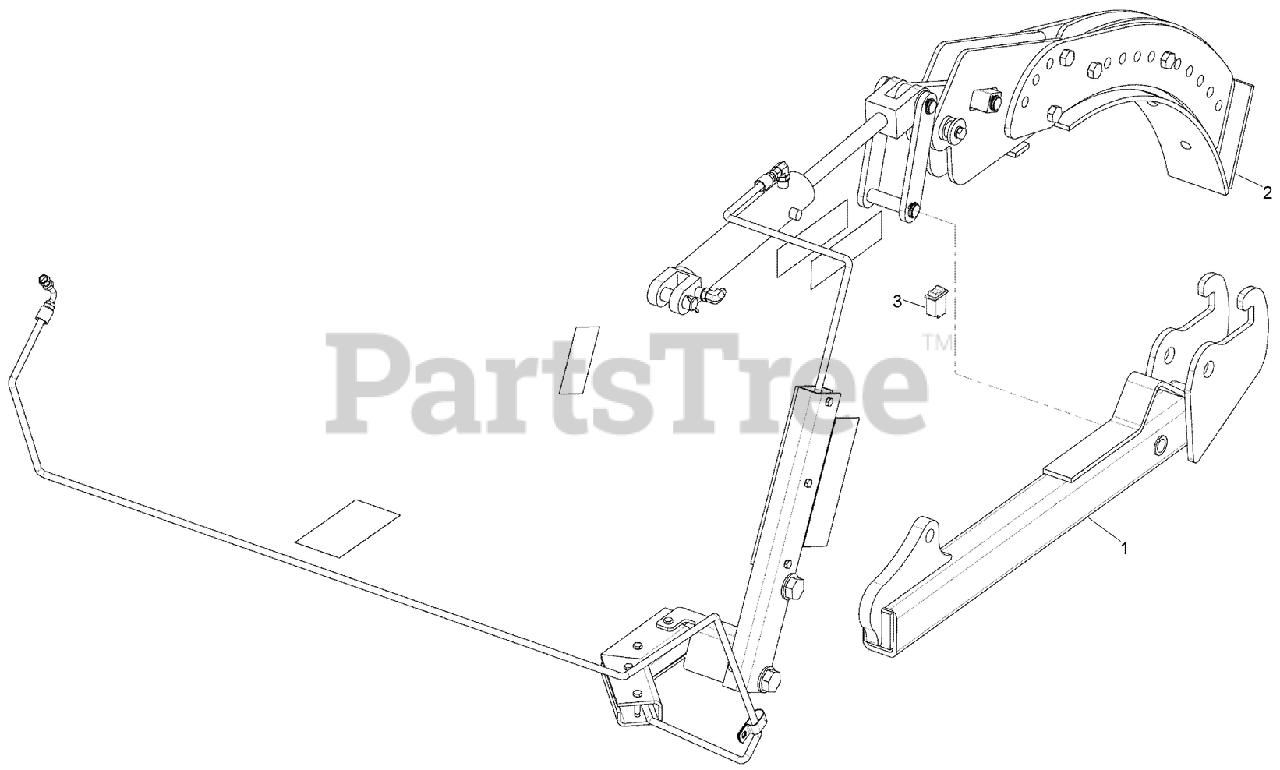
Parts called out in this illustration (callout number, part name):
1	WELDMENT - Tube, 4 Ft Crumber
2	KIT - Hydraulic Crumber
3	SWITCH-ROCKER, 2 POLE
5	BLADE - Hydraulic Crumber, 8 Wide Cut
